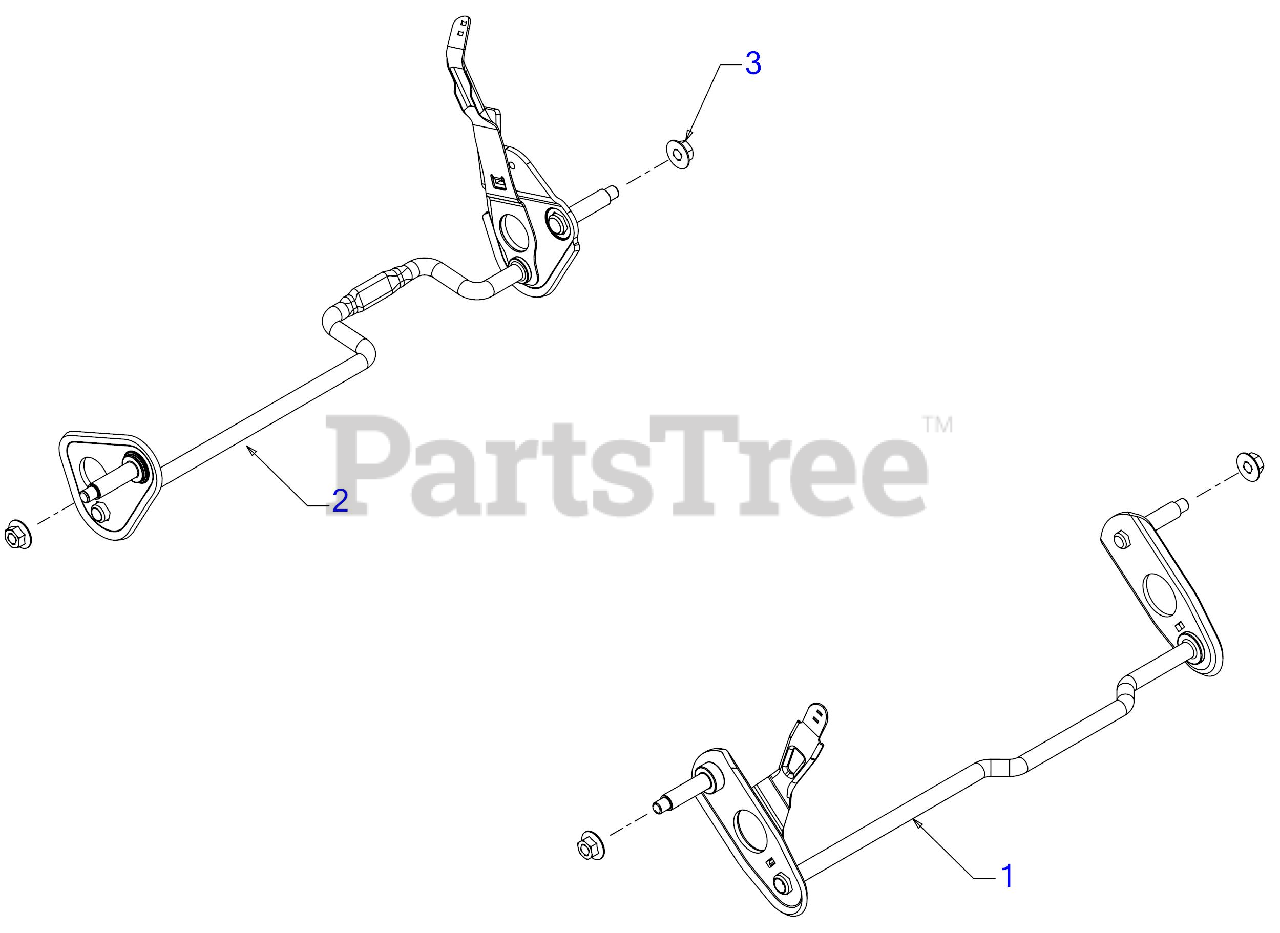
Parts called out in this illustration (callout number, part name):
1	8" FRONT AXLE ASSEMBLY
2	REAR AXLE ASSEMBLY
3	FLANGE LOCK NUT
